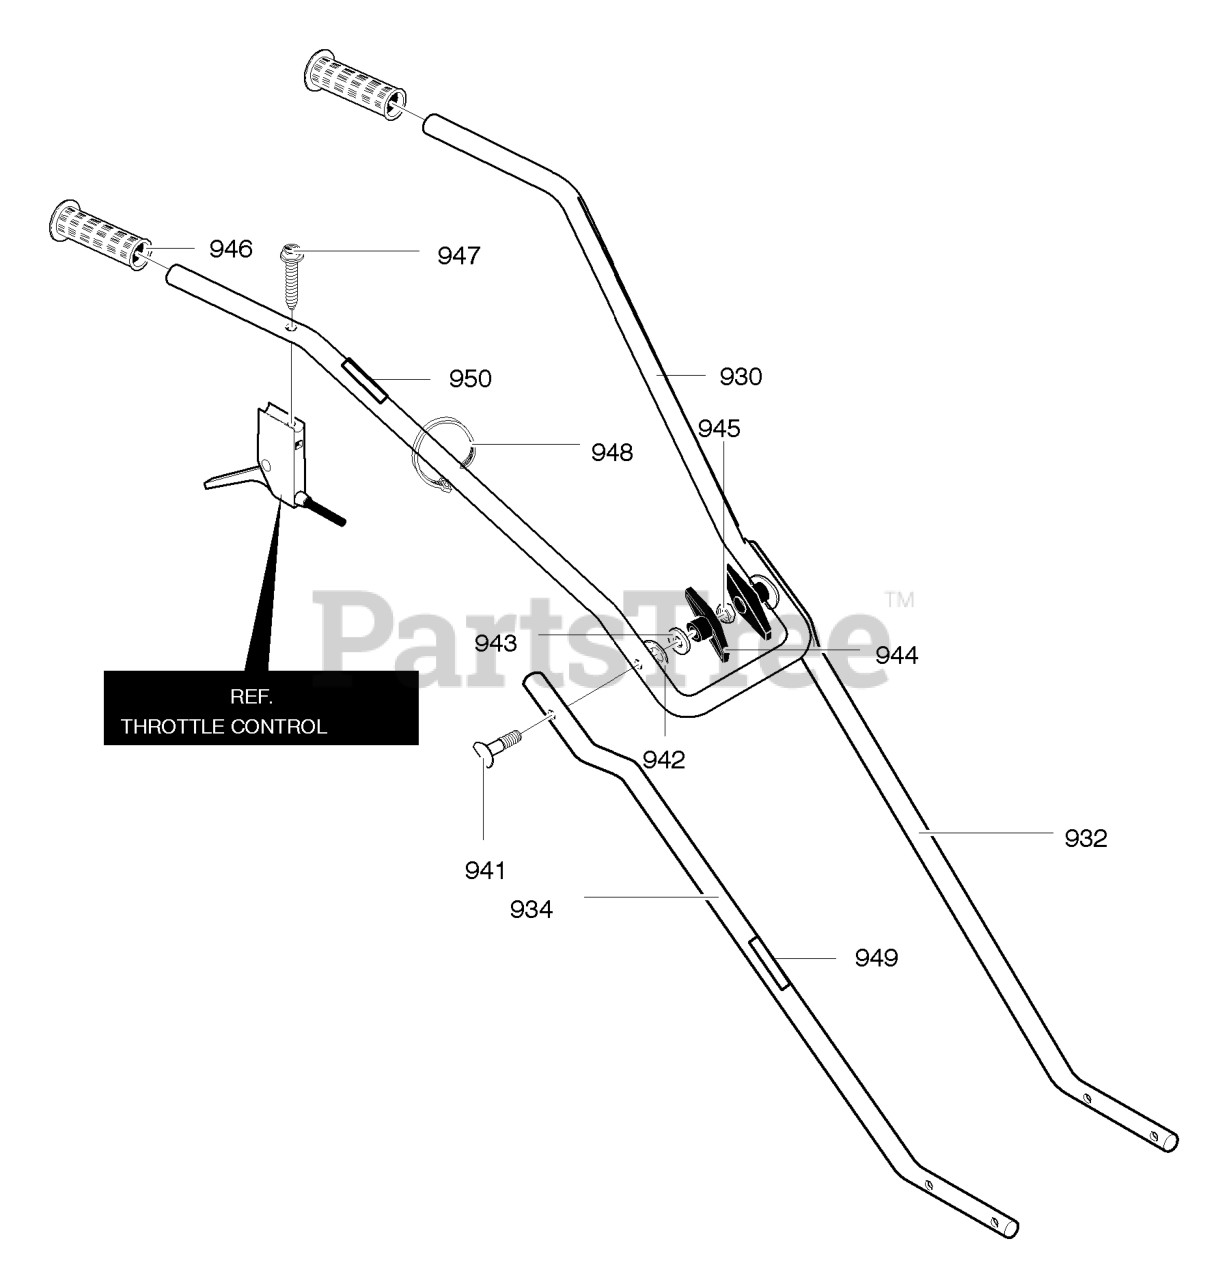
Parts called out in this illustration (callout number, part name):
930	Upper Handle
932	Lower Handle LH
934	Lower Handle RH
941	Bolt 5/16-18x1.63
942	Formed Washer
943	Flat washer
944	T Knob
945	Nut, 5/16-18
946	Hand Grip
947	Screw 10-16x1.5
948	Cable Tie
949	Decal, Caution
950	Decal, Throttle Control
